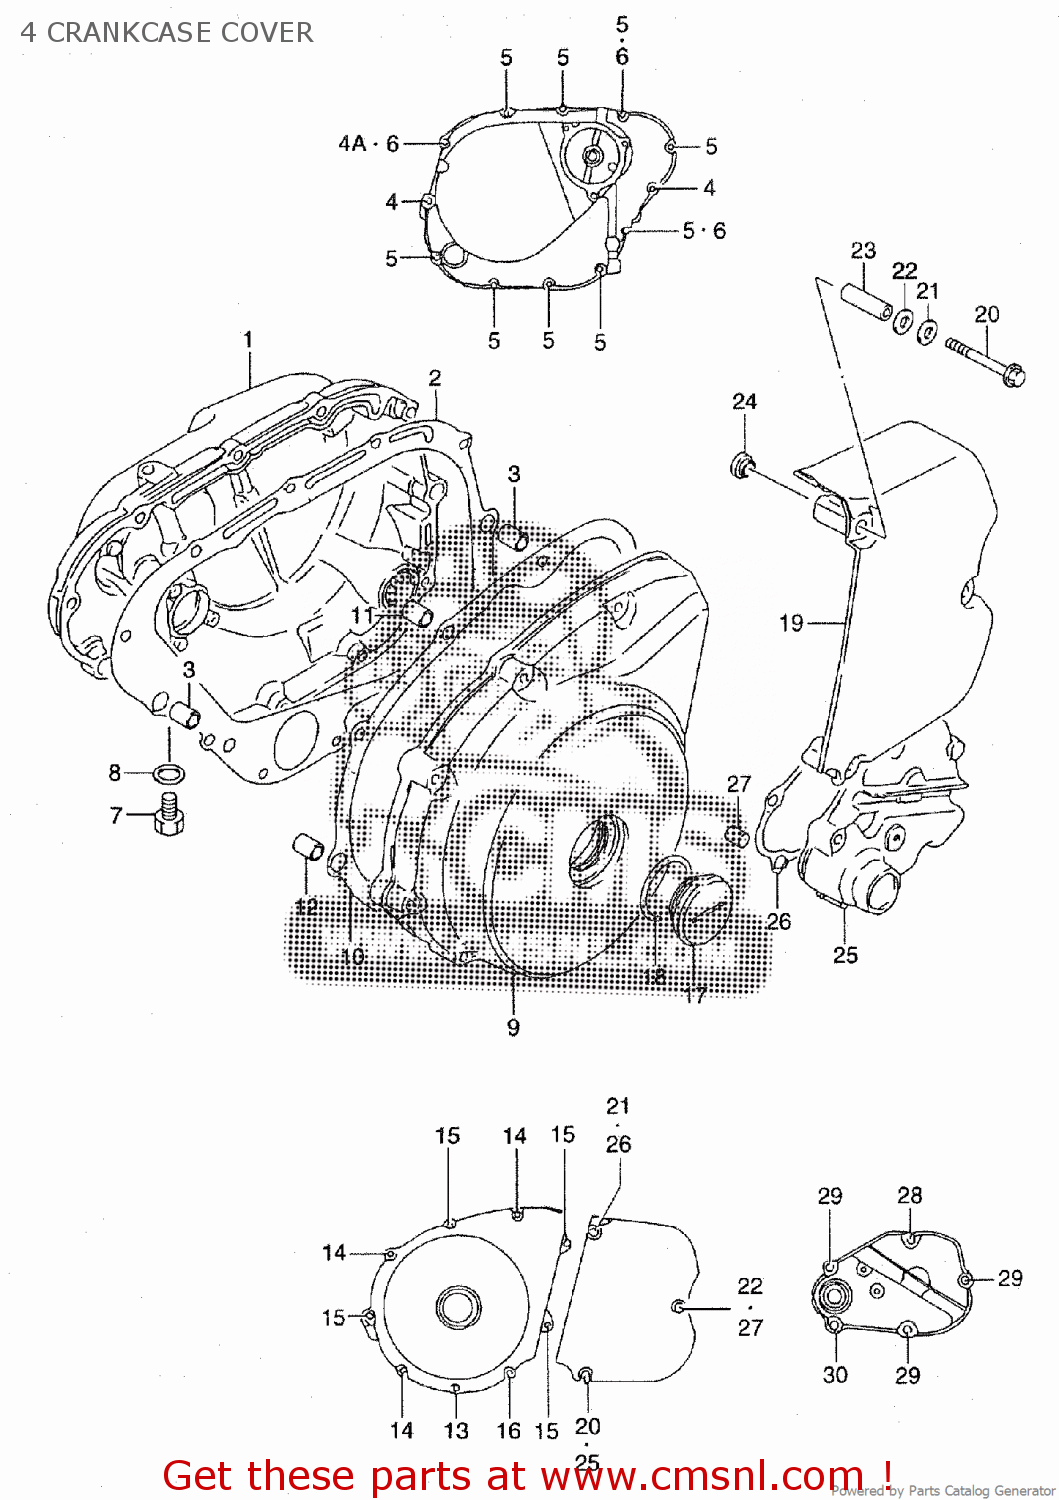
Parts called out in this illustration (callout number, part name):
1	COVER,CLUTCH
2	GASKET,CLUTCH COVER (NAS)
3	PIN
4	BOLT
4A	BOLT
5	BOLT
6	GASKET(5.8X11X1.2) (NAS)
7	PLUG,12X9
8	GASKET(12.1X16.2X3.7) (NAS)
9	COVER,GENERATOR
10	GASKET,GENERATOR COVER (NAS)
11	PIN
12	PIN
13	BOLT
14	BOLT
15	BOLT
16	BOLT
17	PLUG,36X10
18	O RING(D:3.1,ID:32.7)
20	BOLT
21	WASHER(6.5X14X1.6)
22	WASHER(8.7X15X2.1)
23	SPACER(6.5X9X31.5)
24	WASHER(8.7X16X5)
25	COVER,GEAR SHIFT
26	GASKET,GEAR SHIFT COVER (NAS)
27	PIN
28	BOLT
29	BOLT,G/S SWITC
30	BOLT
